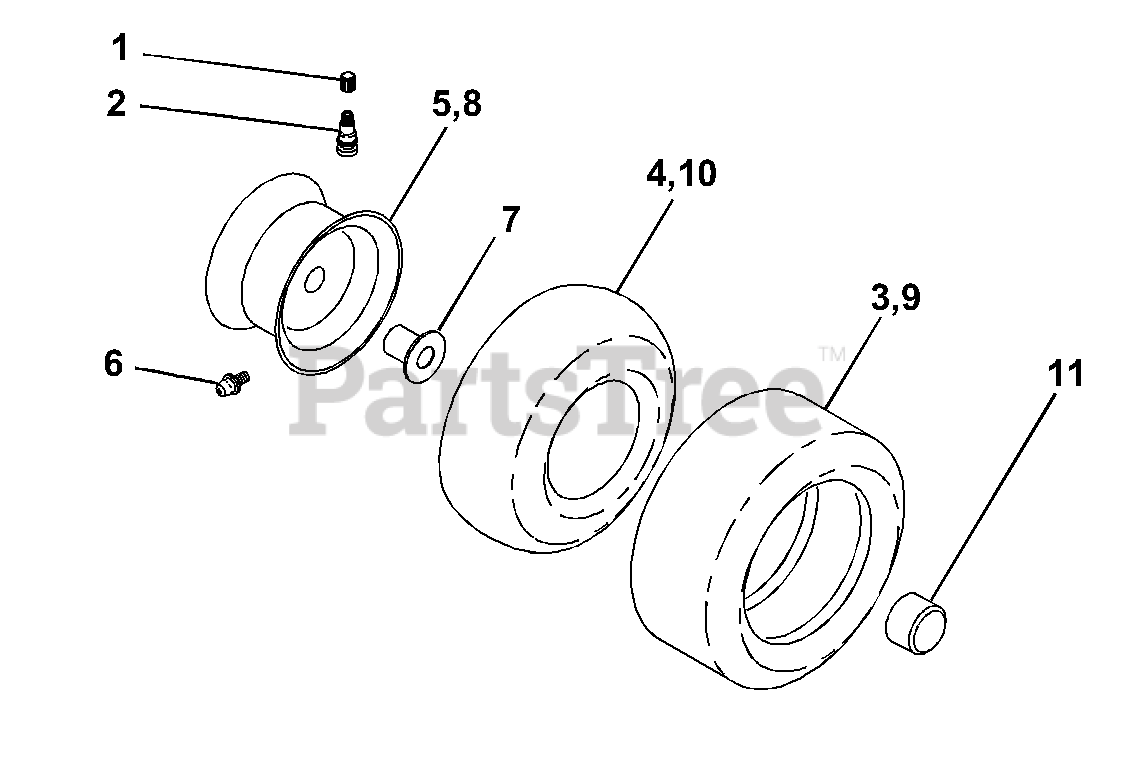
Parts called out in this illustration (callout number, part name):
1	Cap Valve Tire
2	Stem Valve
3	Tire F Ts 15 X 6 0 - 6 Service
4	Tube Front
5	Rim Asm 6"front Silver Service
6	Fitting Grease
7	Bearing Flange
8	Rim Asm 8"rear Silver Service
9	Tire R Ts 18x8 5-8 C Service
10	Tube Rear
11	Cap Axle Blk 1 50 X 1 00
